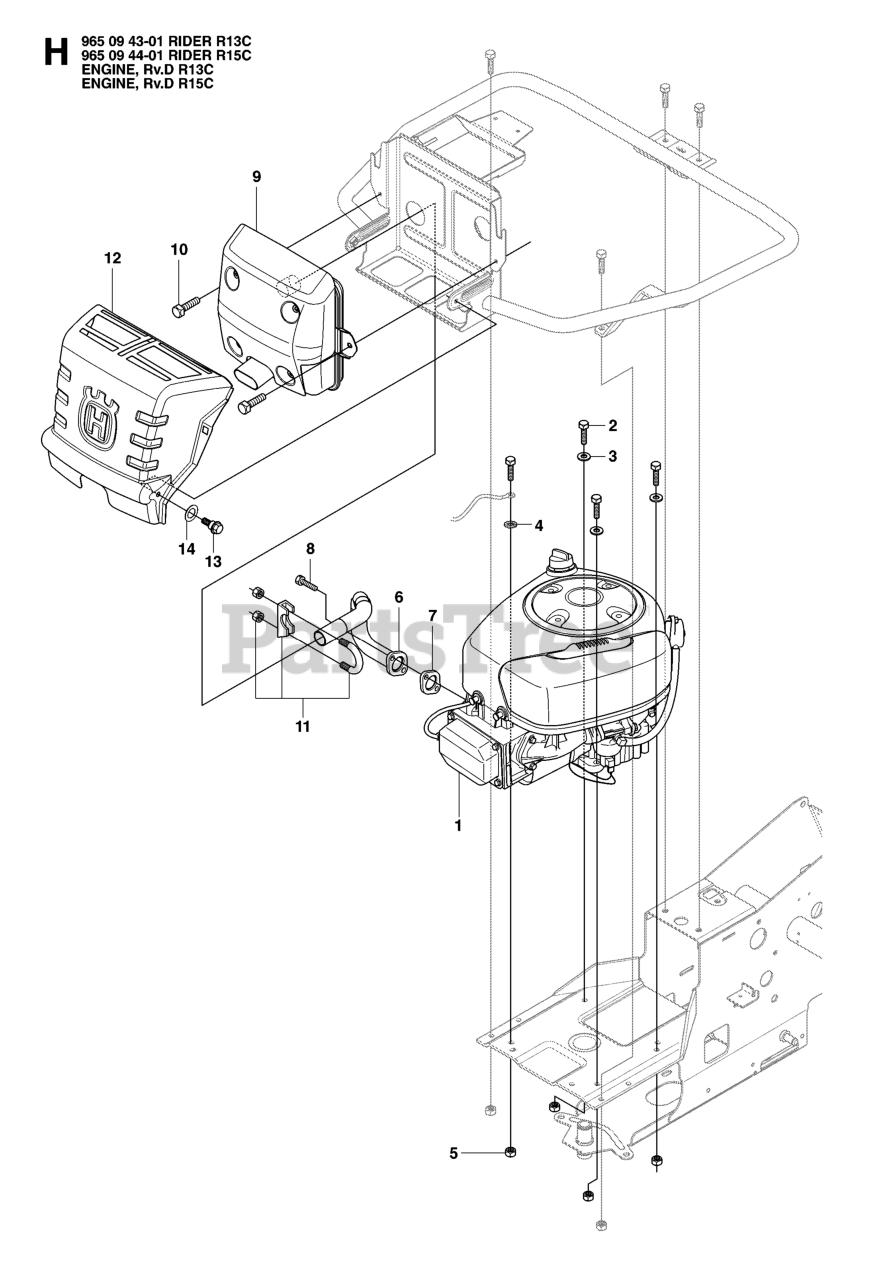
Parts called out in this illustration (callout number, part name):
3	WASHER BRB 8.4X17
5	NUT
6	EXHAUST PIPE ASSY
9	MUFFLER ASSY
11	CLAMP
12	HEAT PROTECTOR
14	SPRINGWASHER
